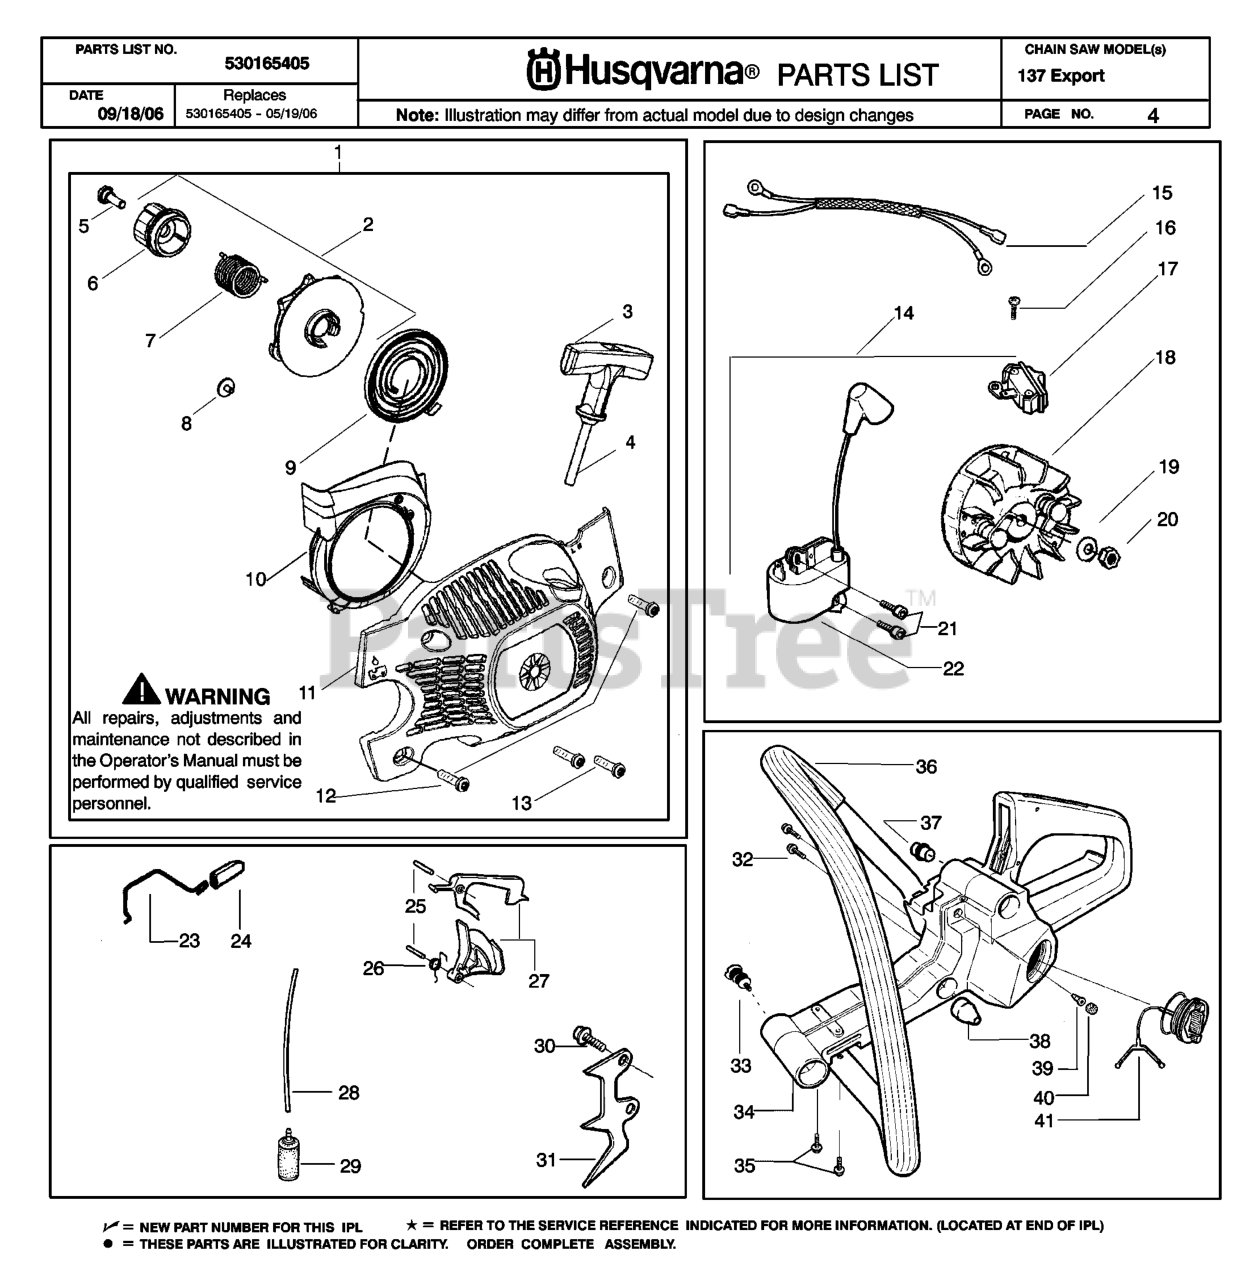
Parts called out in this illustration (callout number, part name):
1	IGNITION MODULE MB50
2	SPARK PLUG CONNECTION
6	SPRING
7	SCREW
8	SPARK PLUG RCJ6Y NLA
10	WASHER, CLUTCH
15	FLANGE NUT
